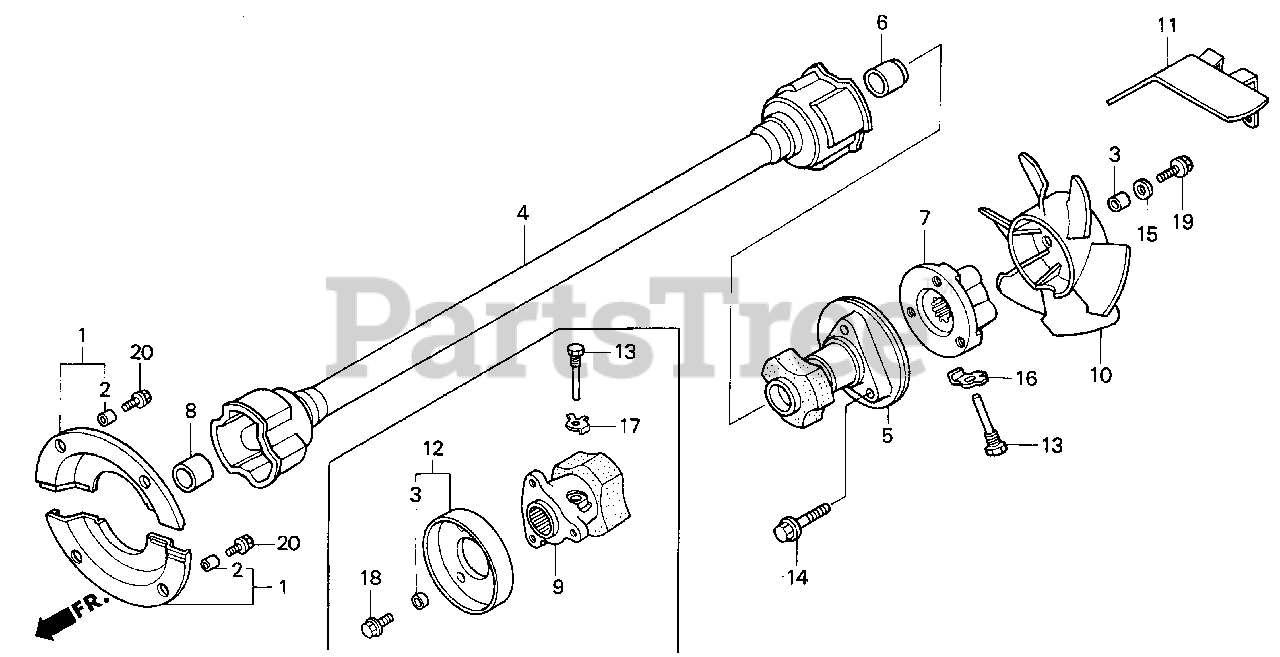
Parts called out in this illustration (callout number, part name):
3	COLLAR, FAN
4	SHAFT, PROPELLER
5	DAMPER A, PROPELLER SHAFT
6	BUSH, CENTERING
7	FLANGE, COMPANION
8	BUSH, CENTERING
9	DAMPER, PROPELLER SHAFT
10	FAN, TRANSMISSION COOLING
11	COVER, TRANSMISSION COOLING FAN
12	COVER, PROPELLER SHAFT (A)
13	BOLT, SPECIAL (8MM)
14	BOLT, UBS (8X33)
15	WASHER, PLAIN (6.5X15)
16	WASHER, LOCK (8MM)
17	WASHER, LOCK (8MM)
18	BOLT, FLANGE (6X12)
19	BOLT, FLANGE (6X14)
